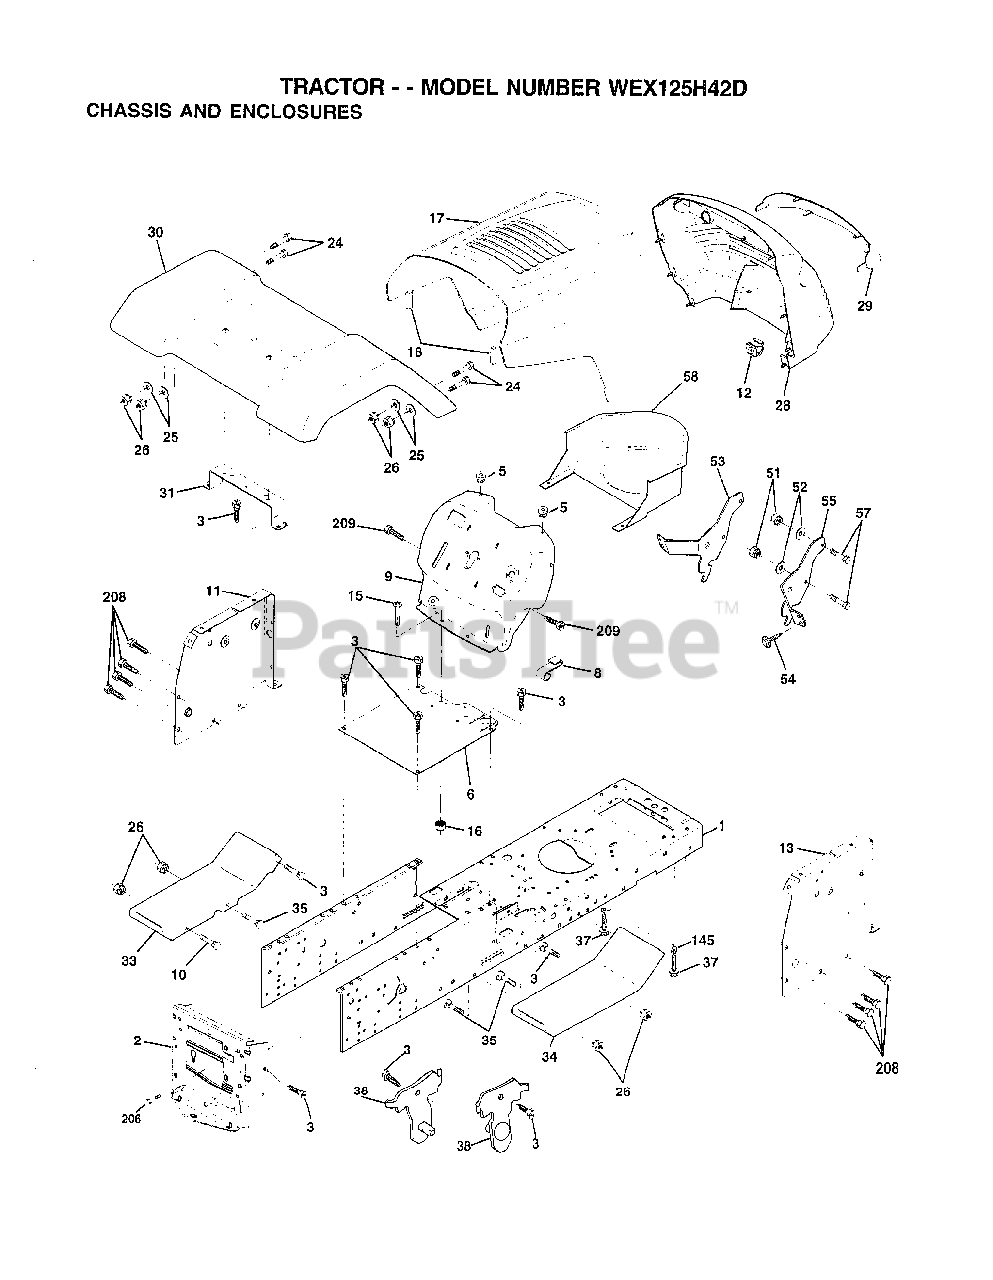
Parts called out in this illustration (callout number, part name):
2	DRAWBAR
3	SCREW
5	BUMPER-HOOD/DASH
6	SADDLE
8	CLIP.RETAINER
9	DASH
11	"PANEL-DASH,LH"
12	CLIP.TINNERMAN
15	SCREW
17	HOOD.STEEL.ASSY
24	BOLT
25	WASHER
26	NUT
28	GRILLE-MS428
29	LENS.GRILLE.PRIVATE LABEL
30	FENDER
31	BRKT FENDER
33	FOOTREST.LH.PERF.
34	FOOTREST.RH.PERF.
35	BOLT
37	SCREW LT
38	BRKT ASM PIVOT MOWER REAR
51	NUT
52	WASHER
53	BRACKET.GRILLE.LH
54	SCREW.HEX.WS.HD
55	BRACKET.GRILLE.RH
58	AIR DUCT
145	"ROD POVOT,CHASSIS"
206	BOLT SHOULDER
208	SCREW
209	SCREW
